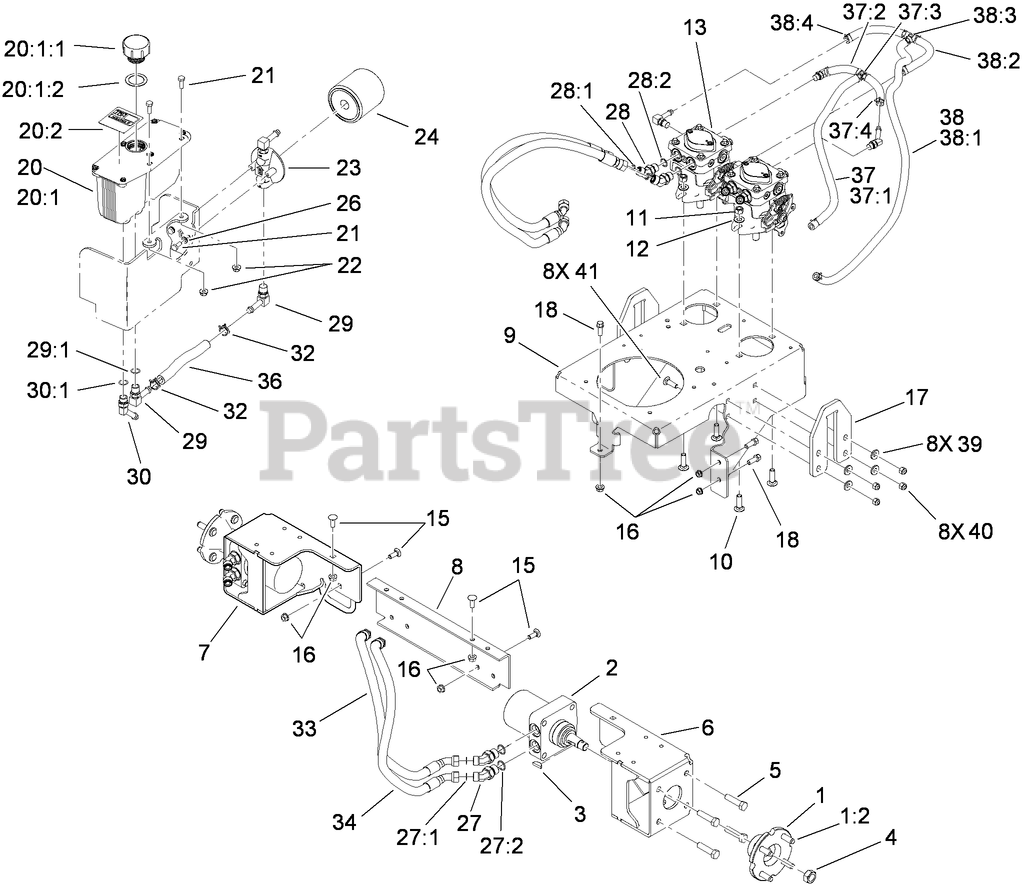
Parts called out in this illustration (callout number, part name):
1	WHEEL HUB ASM
1:2	STUD-TYPE, DRIVE
2	HYD MOTOR ASM
3	KEY-WOODRUFF
4	NUT-MOTOR, WHEEL
5	SCREW-HH
6	LH MOTOR MOUNT ASM
7	RH MOTOR MOUNT ASM
8	MOUNT-MOTOR, CENTER
9	BASE-ENGINE
10	BOLT-CARR
11	NUT-LOCK, NI
12	WASHER-FLAT
13	HYD PUMP ASM
15	SCREW-CARR
16	NUT-HHF, WHIZ
17	PLATE-LIFT
18	SCREW-HWH
20	HYD RESERVOIR ASM
20:1	Reservoir-HYD
20:1:1	CAP-RESERVOIR, HYD
20:1:2	GASKET-CAP
20:2	DECAL-WARNING
21	SCREW-HH
22	NUT-HF
23	HEAD-FILTER
24	FILTER-OIL, HYD
26	WASHER-FLAT
27	FITTING-HYD, 45 DEG
27:1	O-RING
27:2	O-RING
28	FITTING-HYD, 45 DEG
28:1	O-RING
28:2	O-RING
29	FITTING-ELBOW, 90
29:1	O-RING
30	FITTING-BARBED, 45 DEG
30:1	O-RING
32	Clamp-Hose
33	HYD HOSE ASM
34	HYD HOSE ASM
36	HOSE-HYDRAULIC
37	FILTER HOSE ASM
37:1	HOSE-HYDRAULIC
37:2	HOSE-HYDRAULIC
37:3	FITTING-TEE, HOSE
37:4	Clamp-Hose
38	TANK HOSE ASM
38:1	HOSE-HYDRAULIC
38:2	HOSE-HYDRAULIC
38:3	FITTING-TEE, HOSE
38:4	Clamp-Hose
39	WASHER-BELLEVILLE
40	NUT-LOCK, NI
41	BOLT-CARR
